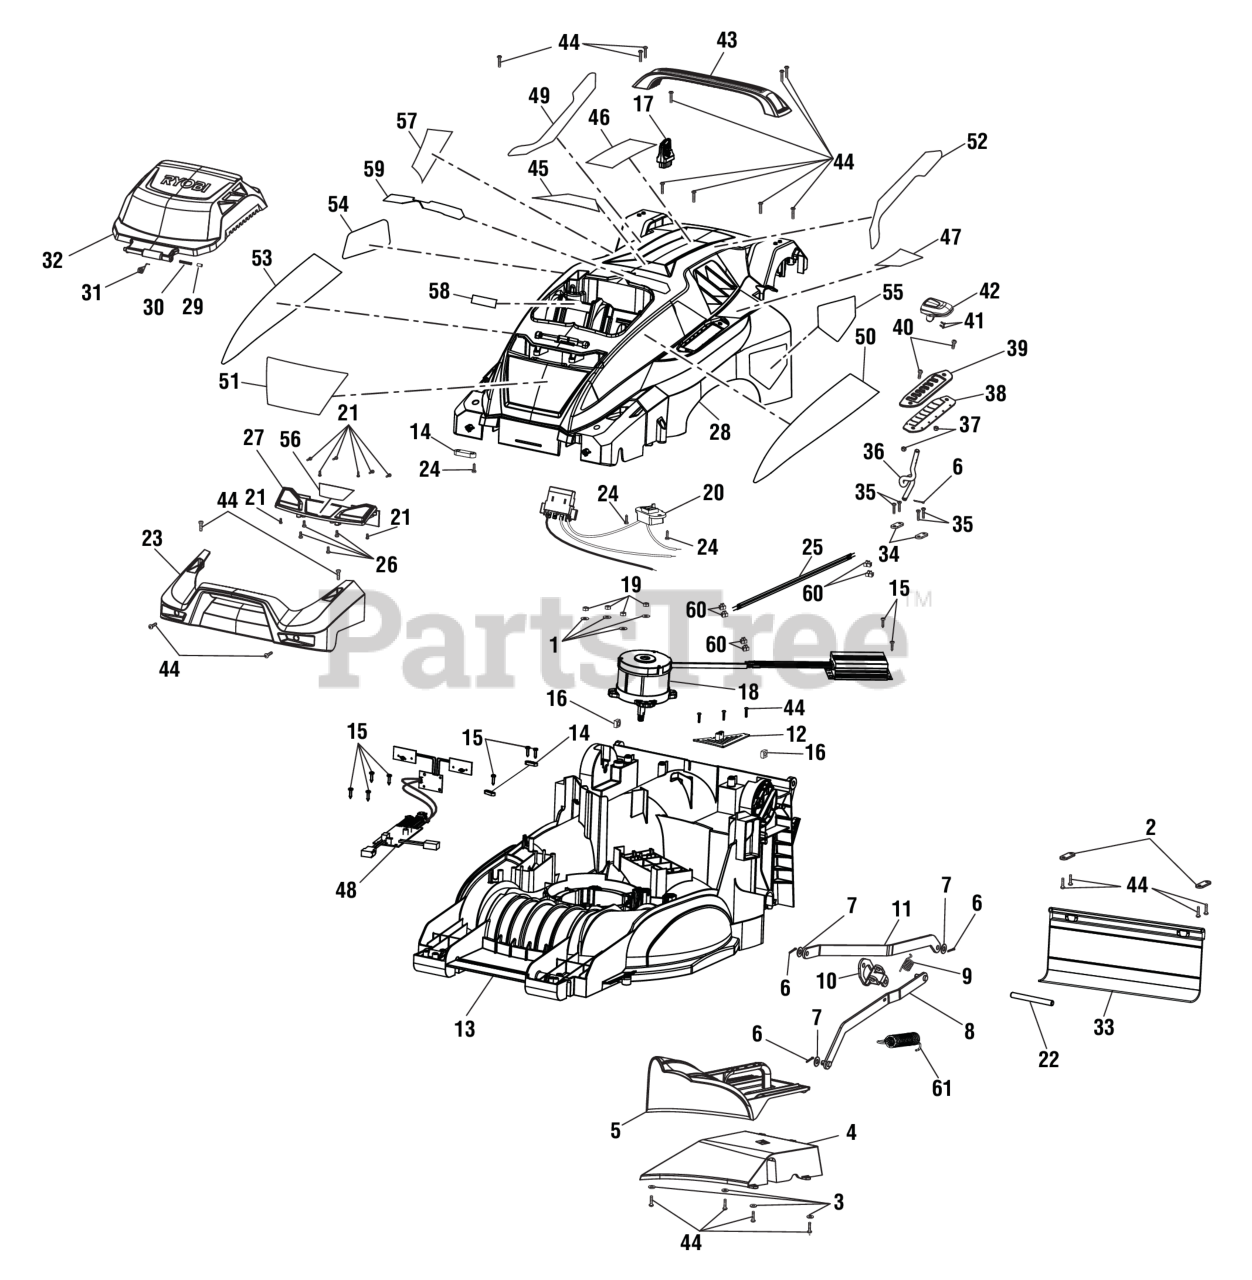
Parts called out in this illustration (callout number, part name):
1	Washer (ID6.2 x OD15 x 0.08t)
2	Axle Pressure Plate
3	Washer (ID4.5 x OD10 x 1t)
5	Mulching Plug
6	Cotter PinÏ? (2.5)
7	Washer (ID8.4 x OD18 x 1t)
8	Front Lift Rod
9	Torsion Spring (Height Adjustment)
10	Height Adjustment Bracket
11	Rear Lift Rod
12	Transmission Cover
14	Wire Press Plate
15	Screw (M4 x 16 mm, T20 Torx Pan Hd.).
16	Square Nut (M8)
17	Start Key
18	Motor and Controller Assembly
19	Lock Nut (M6)
20	Contact Plate Holder Assembly
21	Screw (M3 x 8 mm, Pan Hd., Pan Hd)
22	Axle (Height Adjustment)
23	Front Bumper
24	Screw (M4.2 x 12 mm, T20 Torx Pan Hd.)
25	Inner Wire Connector
26	Screw (M4 x 10 mm, T20 Torx Pan Hd.)
27	Light Assembly w/Label
28	Deck Cover Assembly (Inc. Key Nos. 45-47, 49-55 & 57-59)
29	Battery Door Axle
30	Compression Spring
31	Battery Cover Spring
32	Battery Cover
34	Pressure Plate (Height Adjustment)
35	Screw (M4 x 18 mm, T20 Torx Pan Hd.)
36	Lever Arm
37	Lock Nut (M5 x 0.8 mm)
38	Shifter Boot
39	Height Adjustment Plate
40	SCREW (M5 x 16 mm SOC. WASHER HD. CAP)
41	Screw (M3 x 9 mm, Flat Hd.)
42	Height Adjustment Handle
43	Carrying Handle
44	Screw (M4 x 20 mm, T20 Torx Pan Hd. S.T.)
45	Danger/Warning Icon Label (English)
46	Bilingual Danger (French/Spanish) & Trilingual Warning (English/French/Spanish) Label
47	Height Adjustment Label
48	Circuit Board w/LED Assembly
49	Stripe Label (Right)
50	Brushless Label (Left)
51	40V Self Propelled Logo Label
52	Stripe Label (Left)
53	Brushless Label (Right)
54	Data Label
55	Danger Label (No Hands/Feet)
56	LED Headlight Label
57	40V Lithium Label
58	On Board Battery Storage Label
59	Start Key Label
60	Terminal Block w/Screw
61	Rentention Spring
